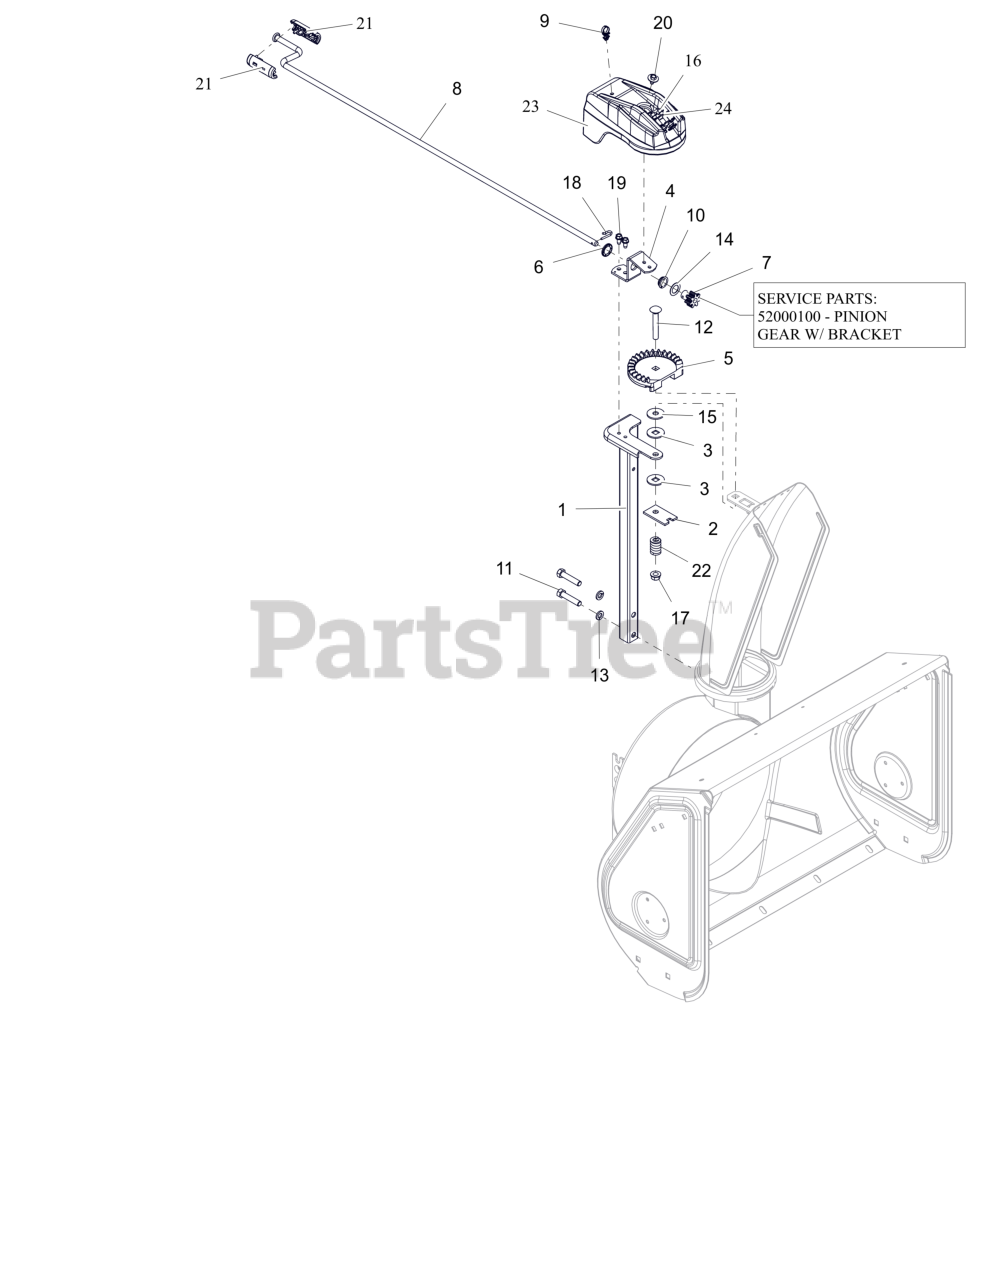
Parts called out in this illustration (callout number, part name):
1	CHUTE PEDESTAL, TALL COMPACT
2	PLATE, FRICTION
3	FRICTION WASHER
4	BRACKET, PINION GEAR
5	CHUTE GEAR
6	PUSHNUT .625
7	PINION GEAR - CHUTE
7	PINION GEAR W/BRACKET
8	ROD, CHUTE CRANK, COMP&SNOTEK
9	CLIP, CABLE GUIDE
10	BUSHING, POLYLINER-.63 SNAPIN
11	BLT, HEX .38-16X1.75 G5 ZCC
12	BLT,RHSN .38-16X2.50 G5 ZCC
13	WSHR,LK-REG .375X.094 ZCC
14	WSHR-THRST .625 X 1.0 X .03
15	WSHR FL STL .406X1.25X.10ZC120
16	NUT,LK-CTR .25-20 GA ZCC
17	NUT-LK-CTR-FLG .375-16 GF ZCC
18	PIN, SPRING CLIP
19	SCR-TAP .25-20X.50 HWH ZCC
20	SCR, TAP .25-20X.50 LG HWH ZCC
21	KNOB- CRANK-SNAP COMPACT
22	SG-COMP .187X.56X1.62
23	COVER, MOUNT - ICE DRILL
24	SHEAR BOLT WITH NUT
